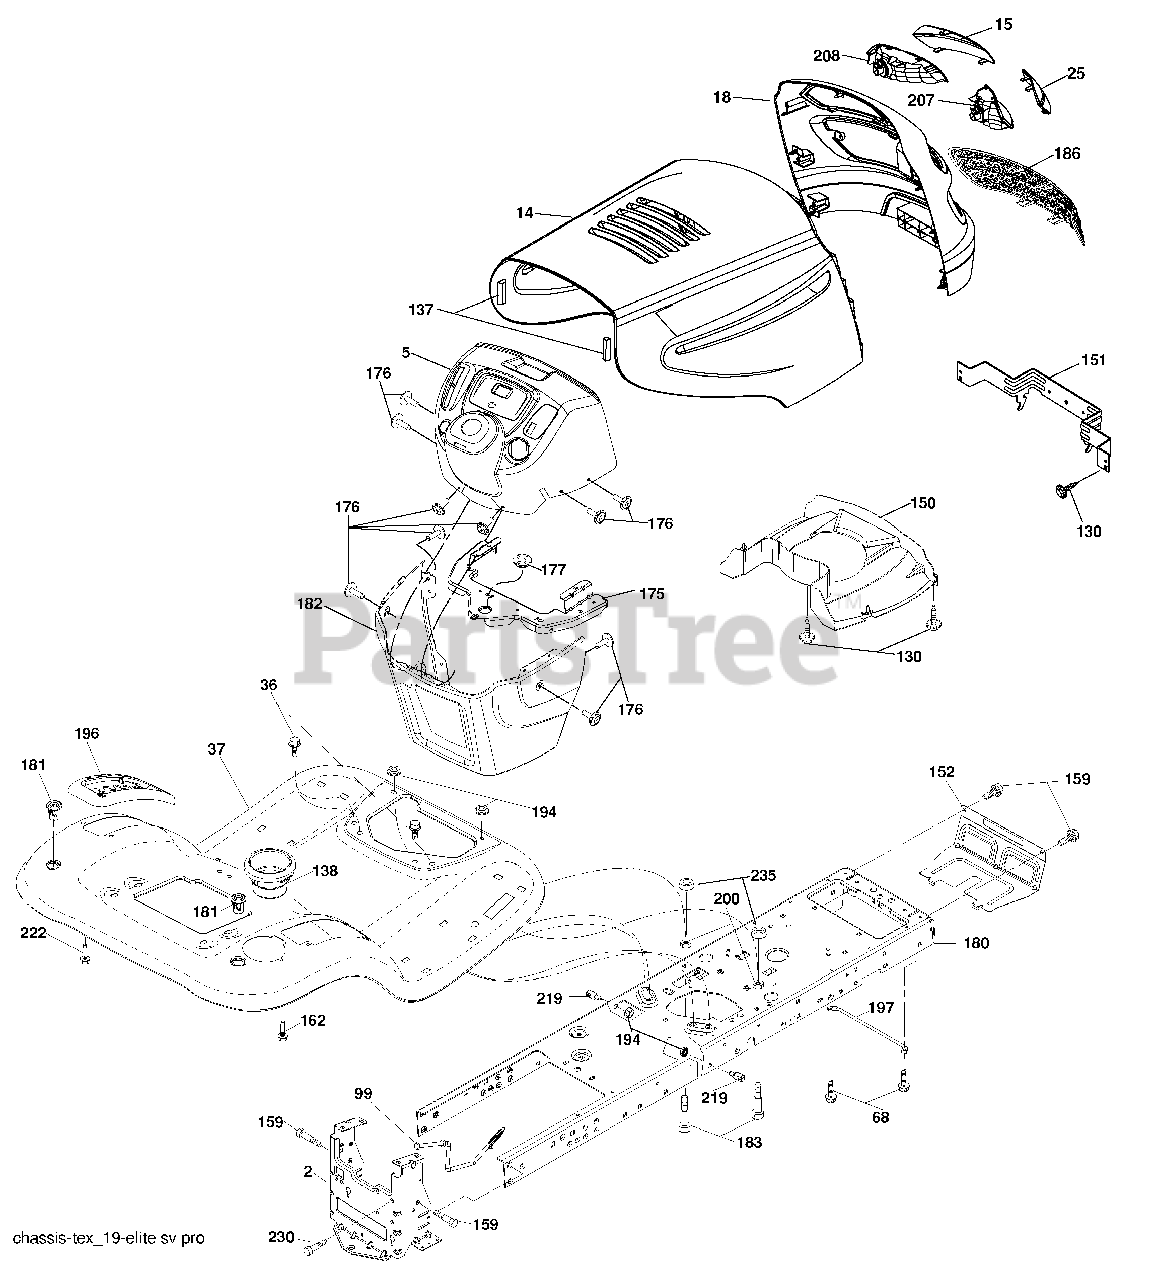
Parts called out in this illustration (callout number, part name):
2	Drawbar
14	Hood
15	Lens Grille LH
18	Grille
25	Lens Grille RH
36	Screw 5/16-18 x 3/4
37	Fender
68	Screw THDROL 5/16-18 x 1/2
99	Rod Bypass Asm
130	Screw 10 x 3/4 Single Lead-Hex
137	Bumper Hood
138	Cupholder
150	Duct Heat Hood
151	Bracket Pivot
152	Shield Browning/Debris
159	Screw Hexwsh Thdrol 3/8-16 x 3/4
162	Screw Hex Wsh Hi-Lo 1/4 x 1/2 unc
175	Crossmember
176	Screw 10-24 x 5/8 Wshd Qdrx
177	Bushing Steering
181	Bushing Mtg. Fender Crgo.
182	Dash Lower
183	Bolt Fin Hex 5/16-18 x 1-1/4
194	Nut Lock Hex Flange 5/16-18
196	Console Asm. Deck Lift
197	Rod Pivot Chassis
200	Nut Center lock 5/16-18
207	Bezel RH
208	Bezel LH
219	Stud Fastener
222	Screw thd Roll 1/4-20 x 5/8
230	Bolt Shoulder 5/16-18
235	Spacer Fender
